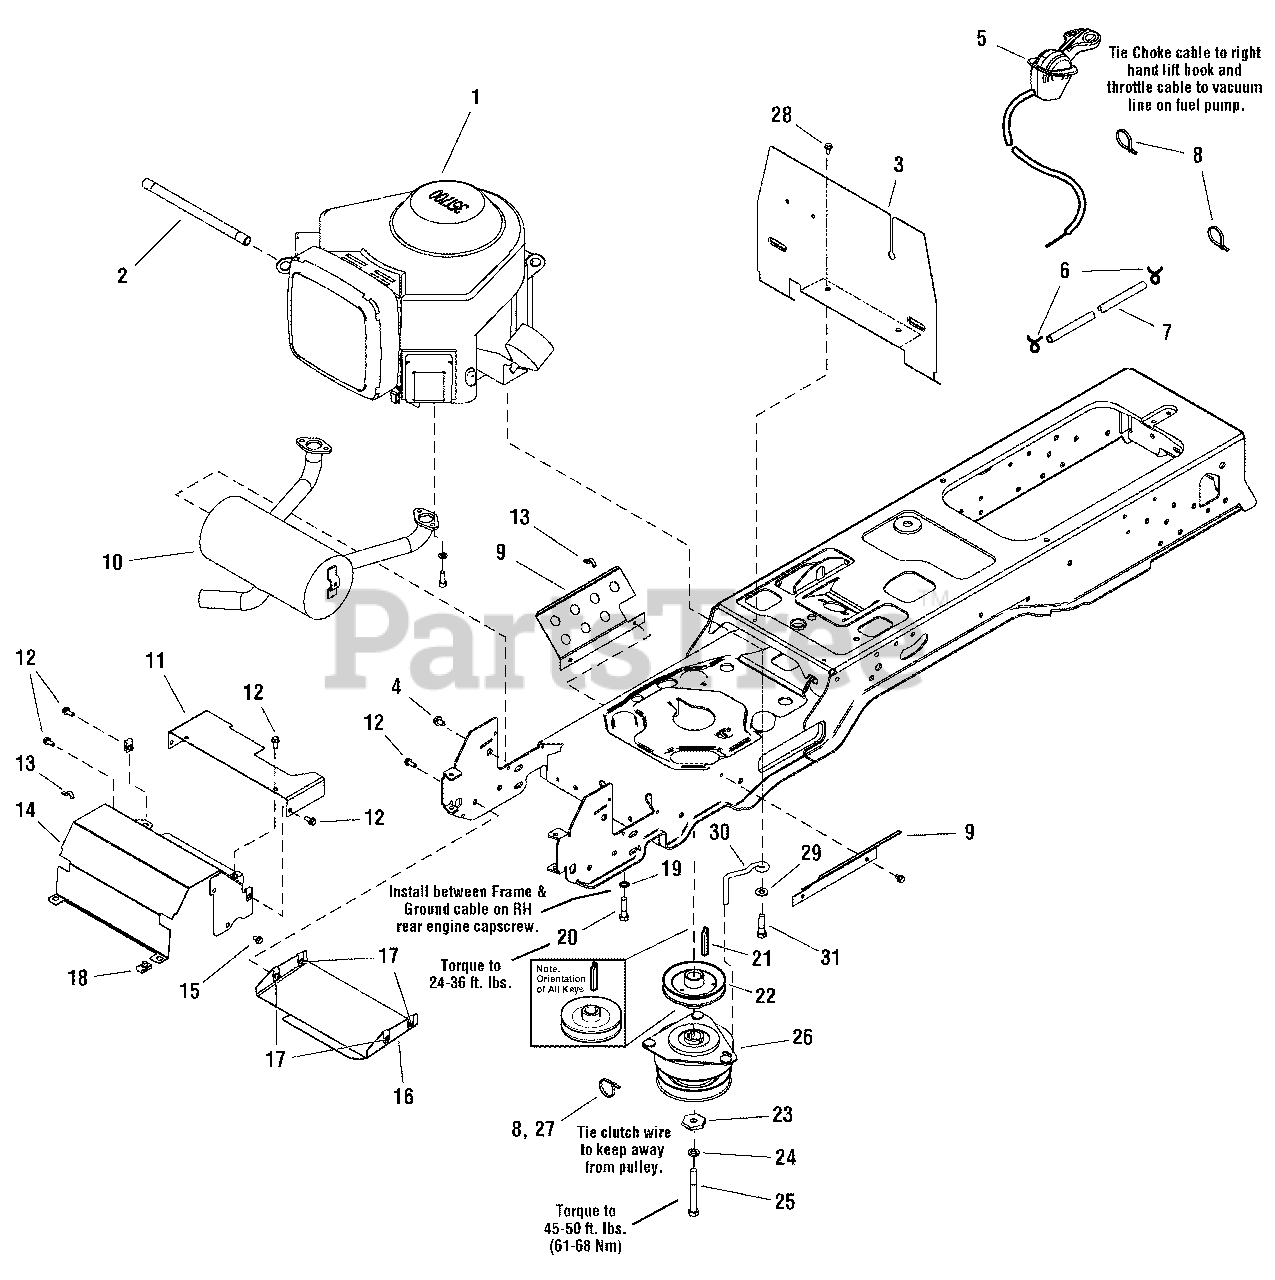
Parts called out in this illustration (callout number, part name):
2	HOSE, Oil Drain
4	SCREW, Hex Washer Head Taptite 5/16-18 x 1/2
5	THROTTLE, Control Double w/Knob
6	CLAMP, Hose 1/2 Diameter Wire Type-E
8	TIE, Self Locking
9	SHIELD, Side 18GA
10	MUFFLER, Kohler Twin
11	DUCT, Muffler Extension 18GA Courage
12	SCREW, Hex Whiz Lock Flange 1/4-20 x 5/8
13	CLIP, Speed Wire
14	DUCT, Muffler Top
15	SCREW, Hex Washer Head Taptite 1/4-20 x 3/8
16	SHIELD, Muffler
17	NUT, Speed 1/4-20 Lug Type
18	NUT, Speed, 5/16-18 Lug Type
19	LOCKWASHER, External Tooth 3/8
20	SCREW, Hex Washer Head Taptite 3/8-16 x 1
21	KEY, Hi-Pro 1/4 x 2-1/2
22	PULLEY & HUB ASSEMBLY
23	WASHER, Hex
24	LOCKWASHER, Spring
25	CAPSCREW, Hex Head 7/16-20 x 3-1/2 G5
26	CLUTCH, Electric
27	TIE, Self Locking
28	SCREW, Hex Washer Head Taptite 1/4-20 x 1/2
29	WASHER, 3/8
30	RETAINER, Clutch
31	SCREW, Hex Washer Head Taptite 3/8-16 x 1-1/2
